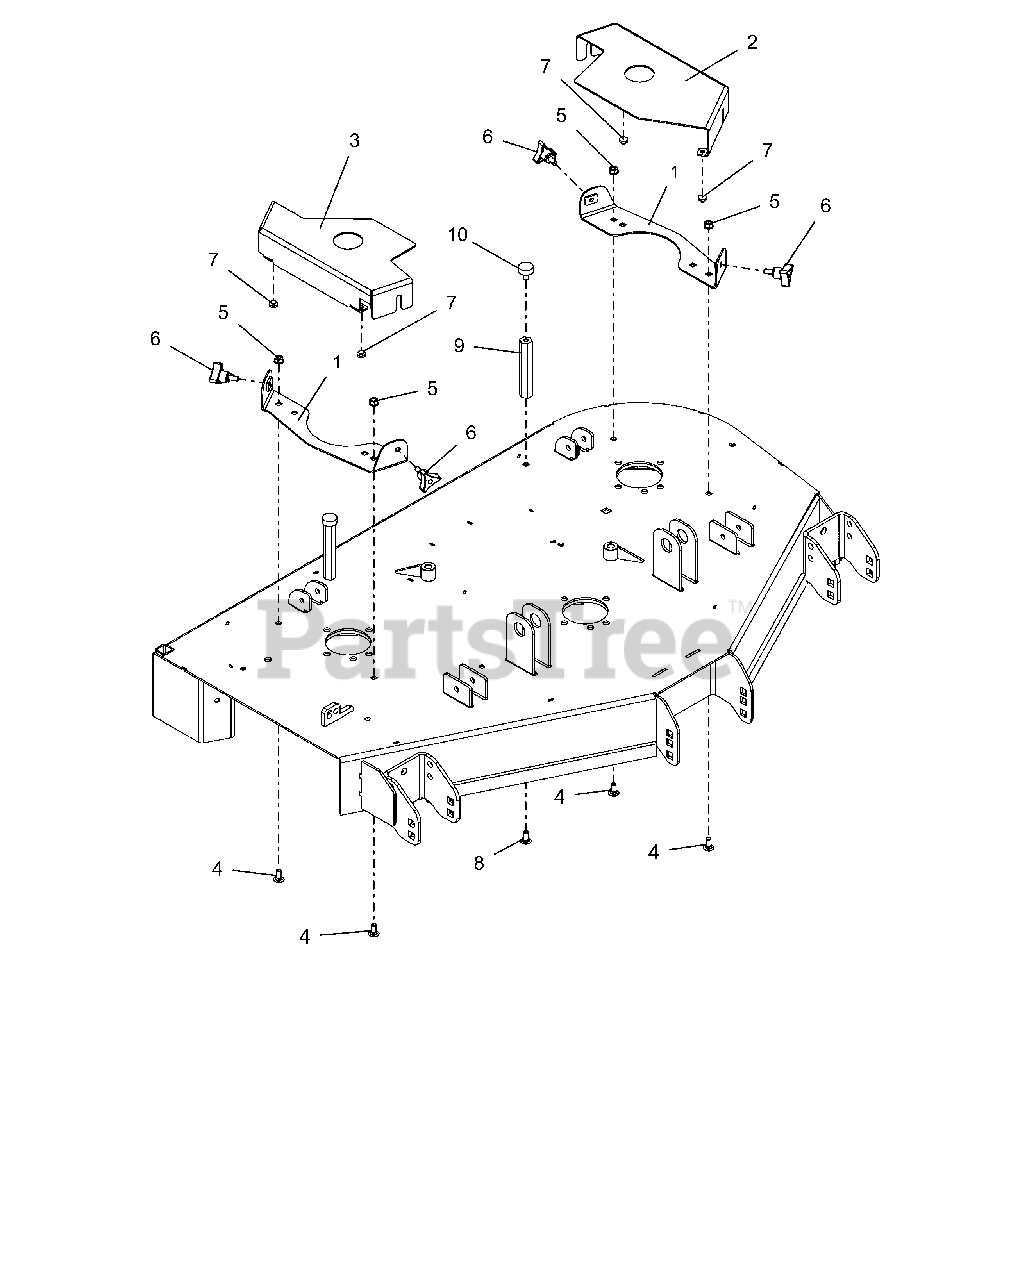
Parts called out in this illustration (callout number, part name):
1	WLDMT, BELT GUARD MTG BRKT
2	GUARD, 44" LH DECK BELT
3	GUARD, RH DECK BELT
4	BLT,RHSN .31-18X.75 G5 ZCC
5	NUT,LK-CTR-FLG .31-18 GF ZCC
6	KNOB,WING STUD 5/16-18 X .75
7	BUMPER GROMMET
8	BLT, RHSSN.31-18X.750 G5 ZCC
9	NUT,.31-18 X 4.125 LG COUPLING
10	BUMPER, RUBBER
